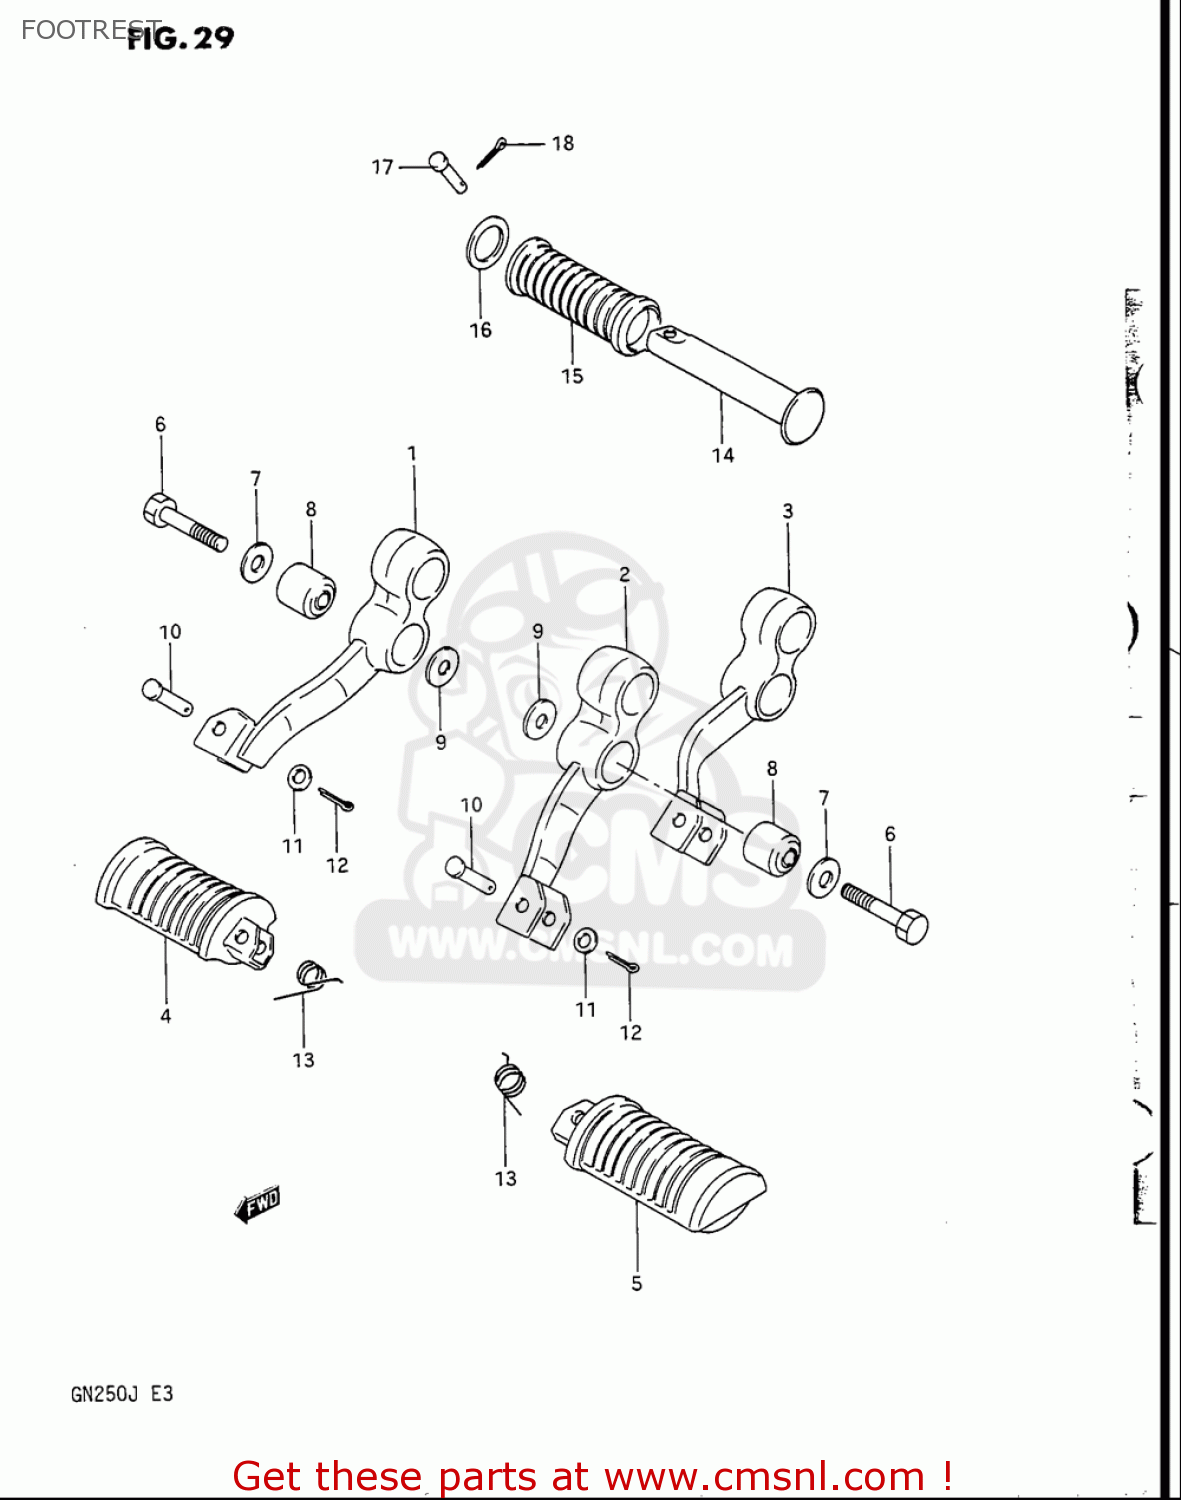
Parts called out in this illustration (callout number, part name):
1	BAR,FRONT FOOTREST,RIGHT
3	BAR,FR FOOTREST,L
4	RUBBER,PILLION FOOTREST,R
5	RUBBER,PILLION FOOTREST,L
6	BOLT(10X35)
7	WASHER(10.1X23X2.3)
8	BUSH
9	WASHER(10X20X2.3)
10	PIN
11	WASHER
12	PIN
13	SPRING
14	BAR,PILLION FOOTREST
15	RUBBER,PILLION FOOTREST
16	WASHER(19.5X32X2)
17	PIN
18	PIN
